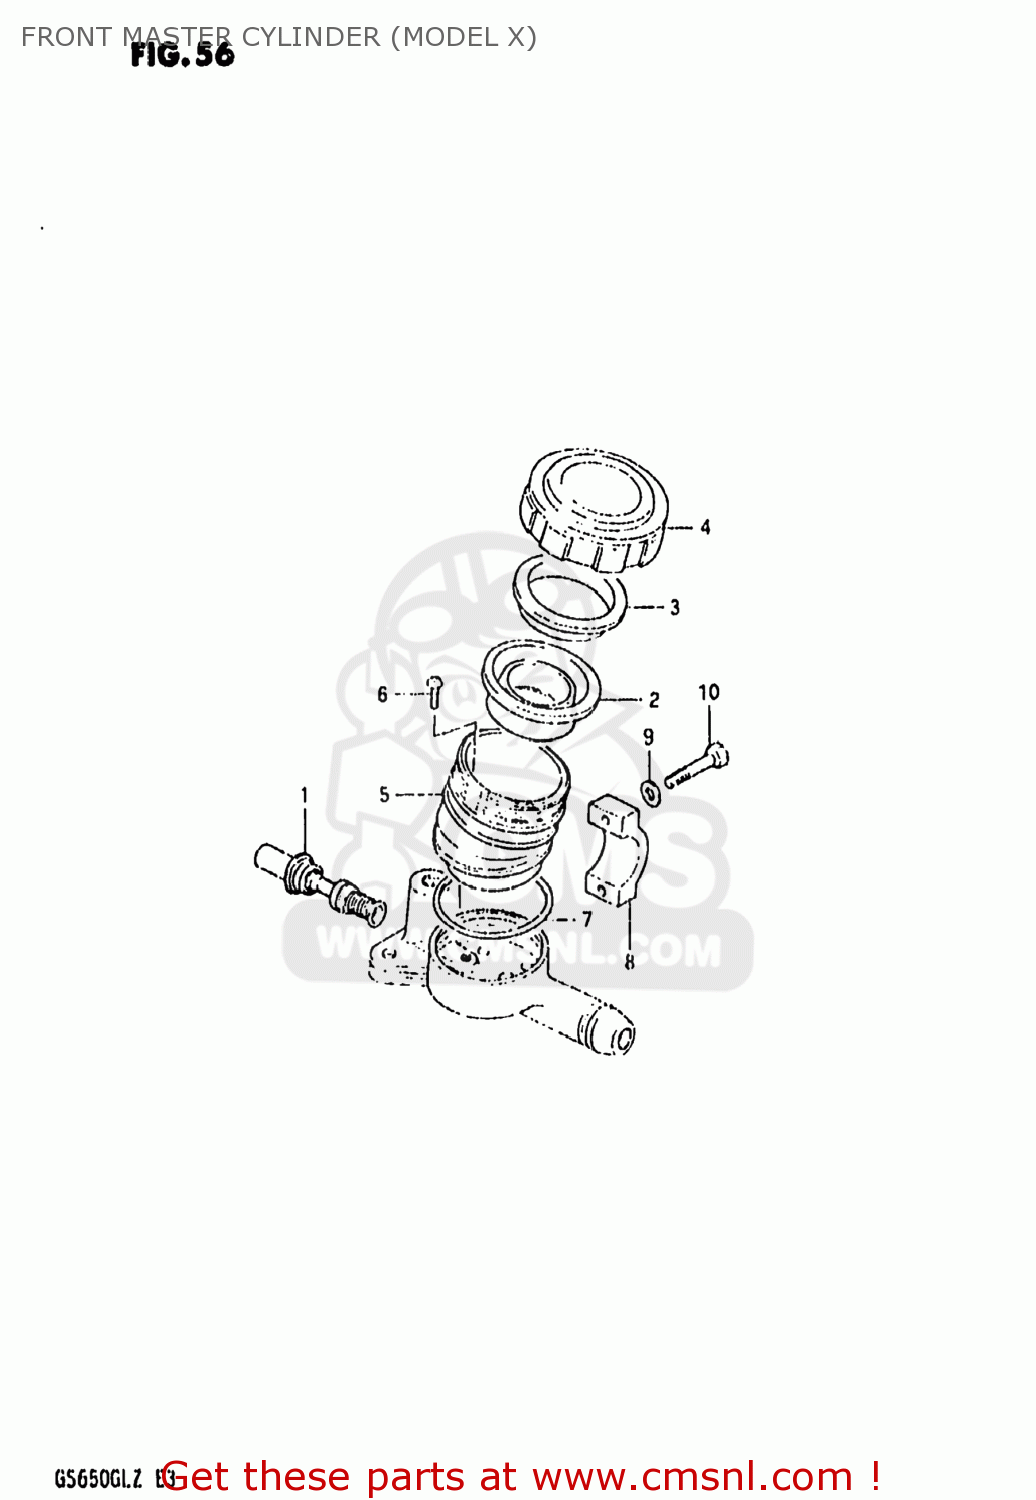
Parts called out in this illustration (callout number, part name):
1	PISTON & CUP SET
2	DIAPHRAGM
3	PLATE,DIAPHRAGM
4	CAP
5	RESERVOIR
6	SCREW,MASTER CYLINDER
7	O RING
8	HOLDER,MASTER CYLINDER
9	WASHER
10	BOLT
